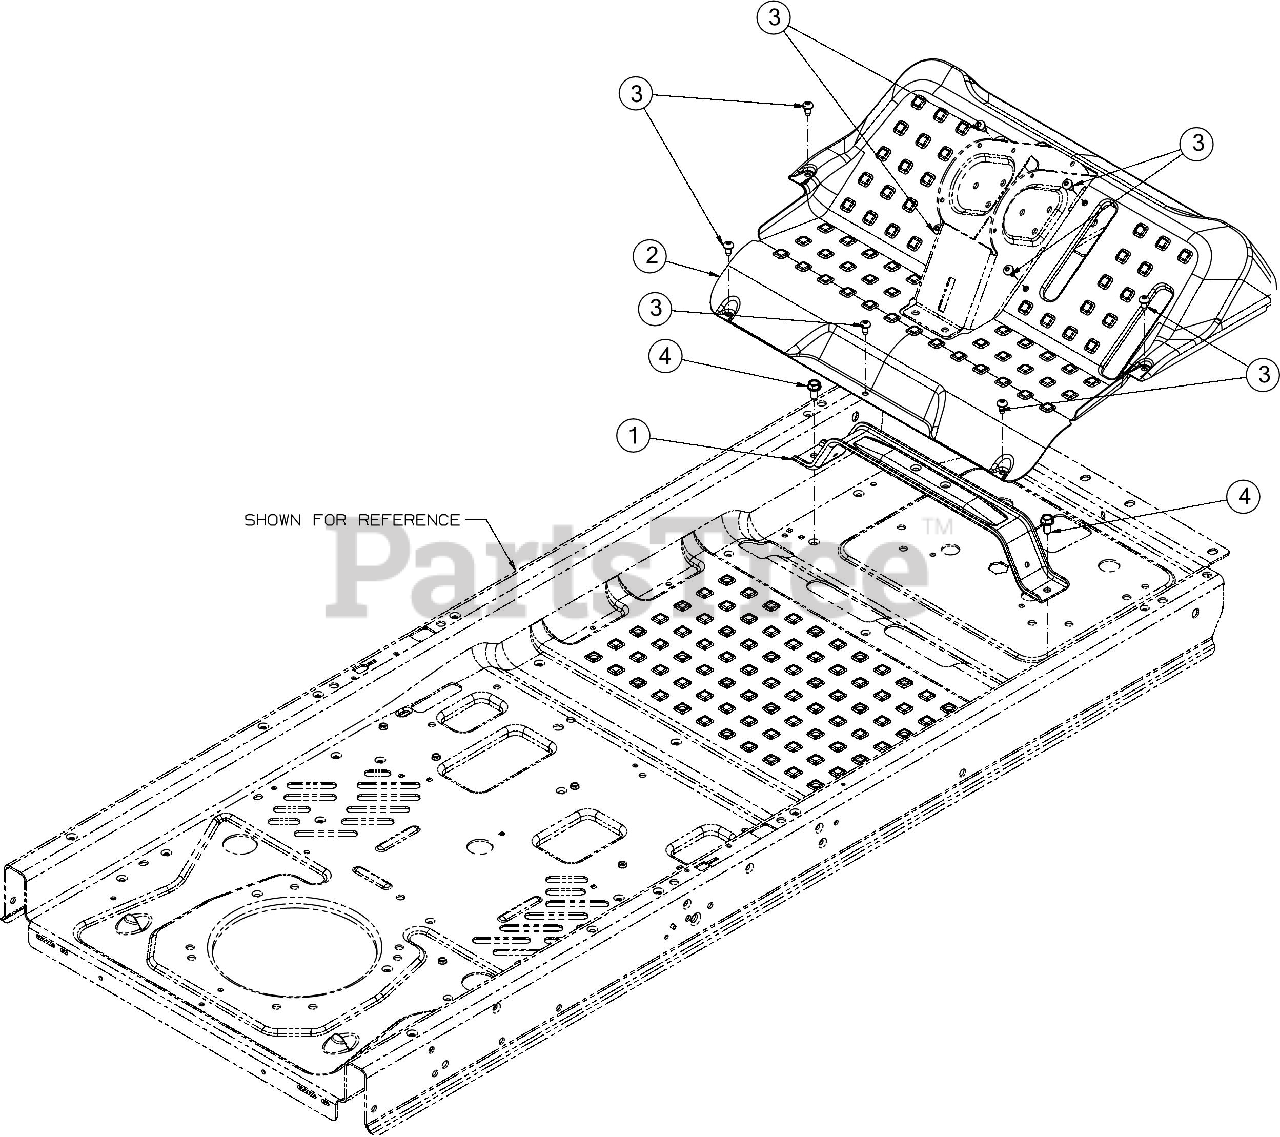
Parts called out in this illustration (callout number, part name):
1	STEERING SUPPORT BRACKET
2	FLOORBOARD
3	SCREW 1/4-20 X .500
4	SCREW 5/16-18 X .750
